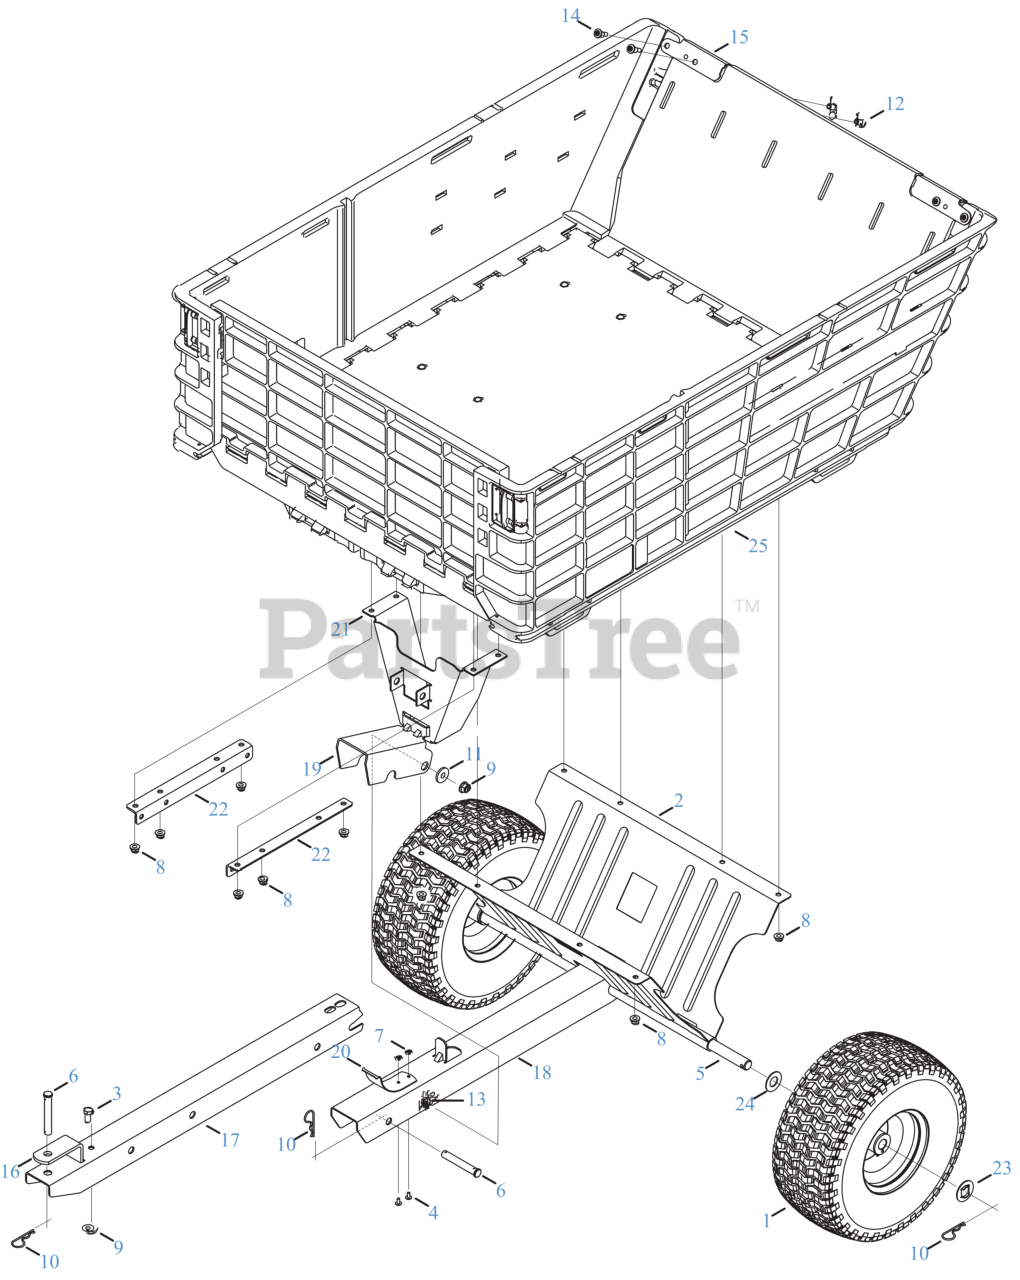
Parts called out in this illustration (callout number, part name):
3	HEX SCREW 3/8-16 x .75
4	SCREW-10 x .393
5	AXLE SHAFT .75 x 29.1
6	CLEVIS PIN: 0.5 x 3.25
8	FLANGE LOCK NUT 5/16-18
10	INTERNAL COTTER PIN
11	SHOULDER SPACER
12	SHOULDER NUT .375 DIA x .5
13	SHOULDER SCREW 3/8-16
14	SHOULDER SCREW: 1/4-20
19	DUMP RELEASE PEDAL
20	RELEASE BRACKET
23	FLAT WASHER .781 ID x 1.59 OD
24	THRUST WASHER
25	Bed Assembly
